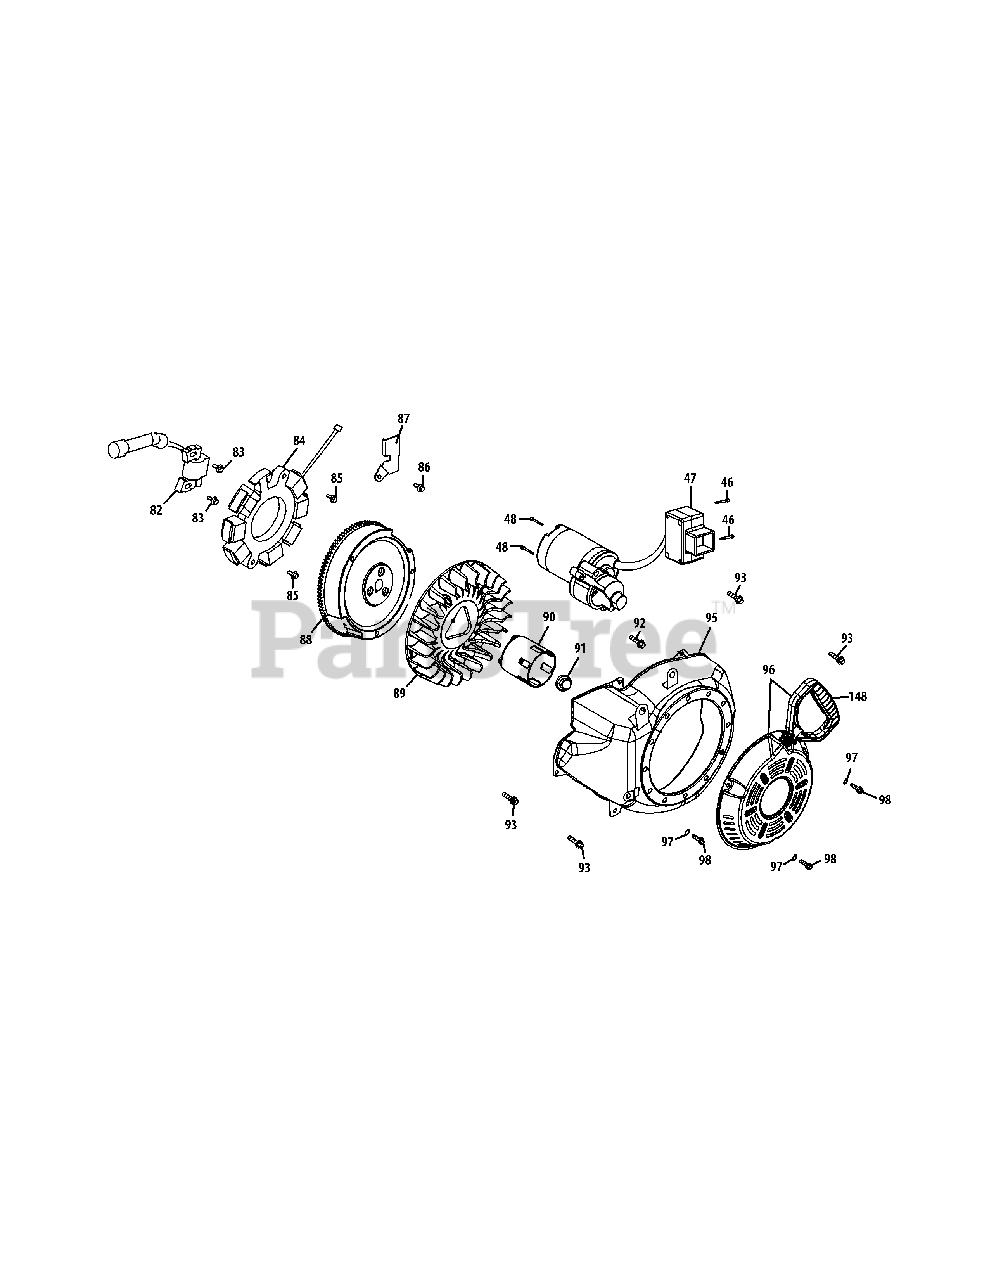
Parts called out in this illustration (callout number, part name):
46	Bolt, M4 x 55
47	Startup Electromotor
48	Bolt, M8 x 55
82	Ignition Coil Ass’y
83	Ignition Coil Bolt
84	Coil Assy. Charge
85	Bolt, M6 x 30
86	Bolt, M6 x 8
87	Alternator Wire Clamp Bracket
88	Flywheel
89	Fan, Cooling
90	Starter Cup
91	Nut, Special, M16 x 1.5
92	Bolt, M6 x 16
93	Bolt, M6 x 12
95	Blower Housing
96	Recoil Starter
97	Gasket
98	Bolt, M6 x 10
148	Starter Handle
